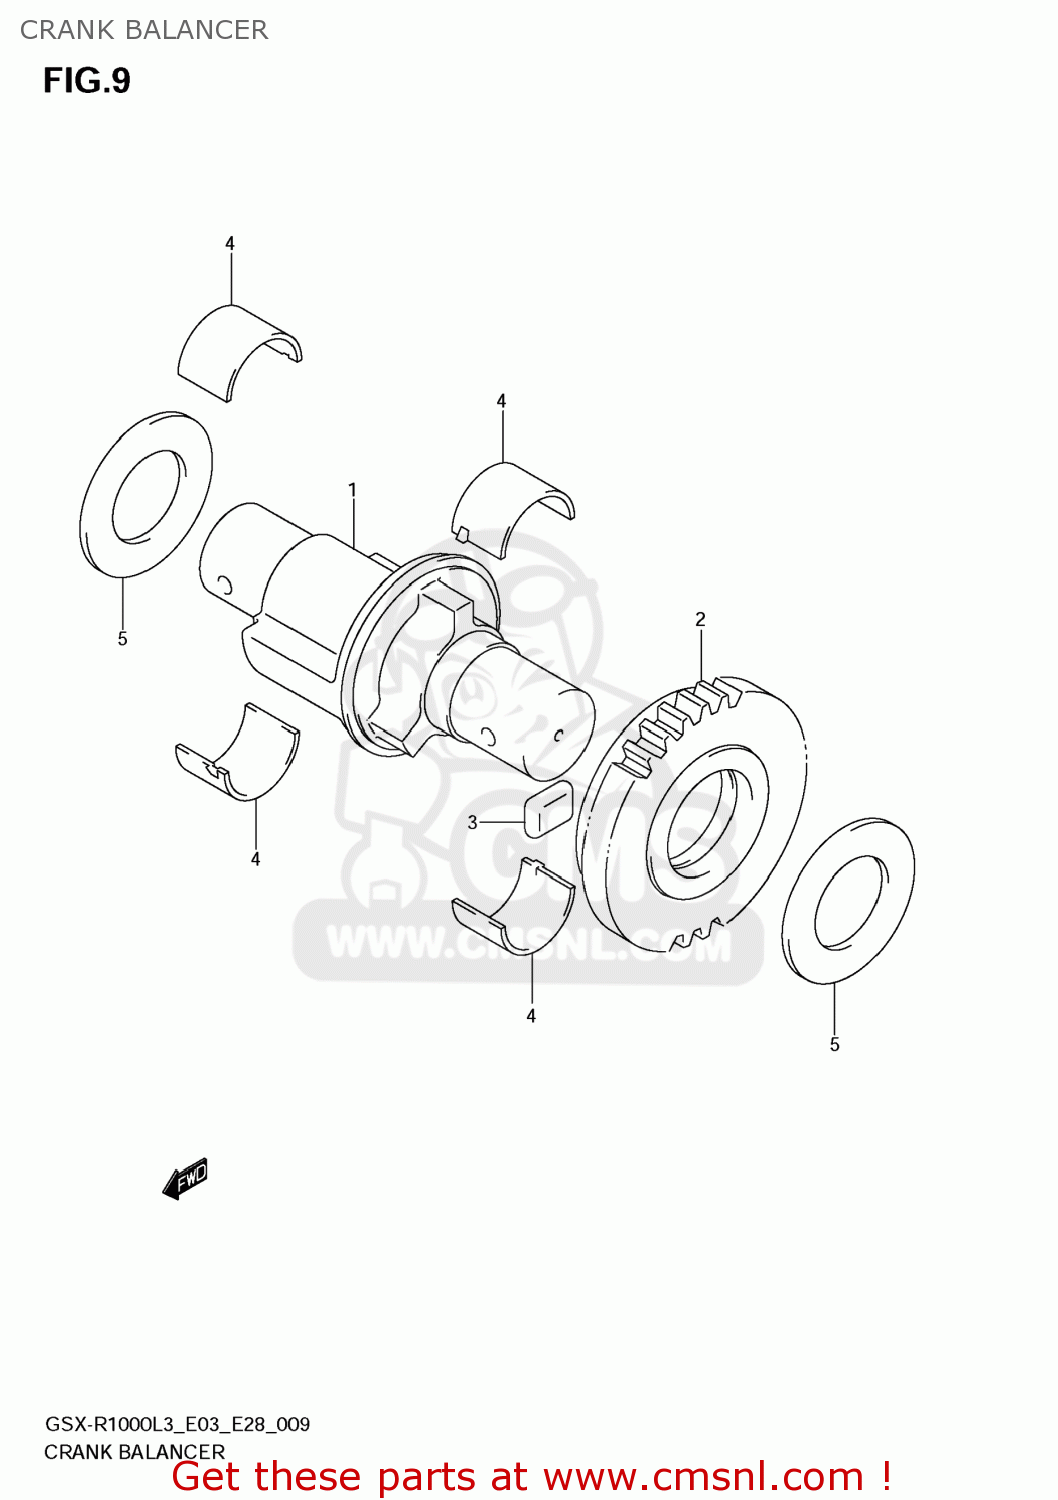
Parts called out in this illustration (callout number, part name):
1	BALANCER,CRANK
2	GEAR,CRANK BALANCER
3	DAMPER,CRANK BALANCER GEAR
4	BEARING,CRANK BALANCER
5	WASHER
